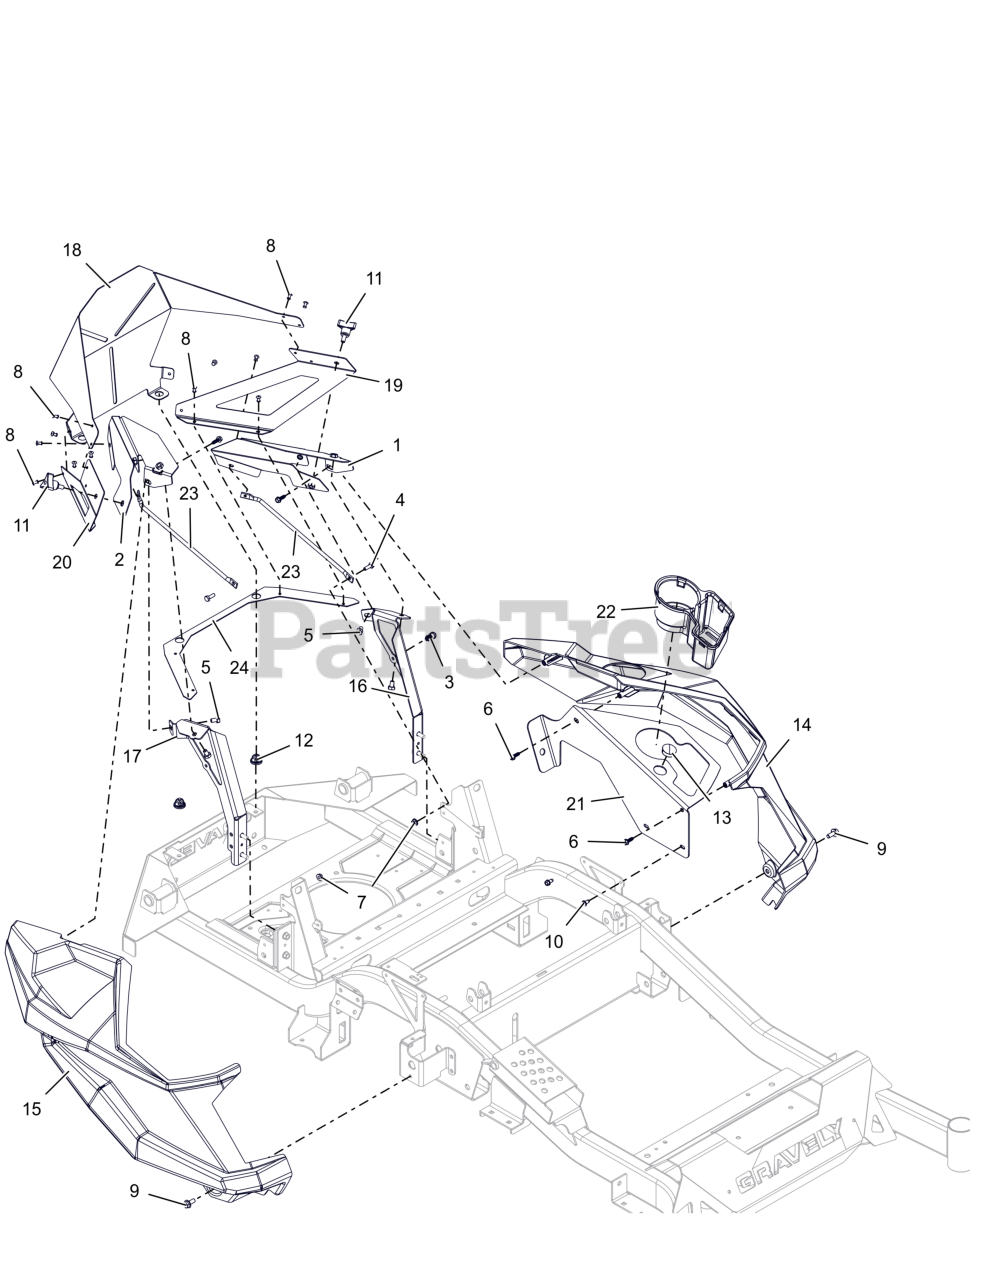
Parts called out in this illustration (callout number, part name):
1	PANEL, LH (RED)
2	PANEL, RH (RED)
3	CLIP, CABLE GUIDE
4	BLT, HEX .25-20X.75 G5 ZCC
5	BLT, HEX .31-18X.50 GR5 ZCC
6	SCR, PLASTITE-HWH 0.25 X 0.75 ZC120
7	NUT-LK-CTR-FLG .25-20 ZC120
8	RIVET, #66 STEEL POP PD BLACK
9	BLT, SERHFWH 0.312-18X0.75 GR5 ZCC
10	SCR-TAP .25-20X.50 HWH ZCC
11	KNOB,WING STUD 5/16-18 X .75
12	GROMMET, 10MM BOLLHOFF
13	PLUG, HOLE 1.125 DOMED
14	FENDER, LH
15	FENDER, RH
16	BRKT, LH FENDER MTG (RED)
17	BRKT, RH FENDER MTG (RED)
18	WRAP, REAR (BLACK)
19	WRAP, REAR - LH (RED)
20	WRAP, REAR - RH (RED)
21	PANEL, HD CUPHOLDER (RED)
22	HOLDER, CUP
23	ROD, STIFFENER
24	STIFFENER, BACK WRAP (RED)
